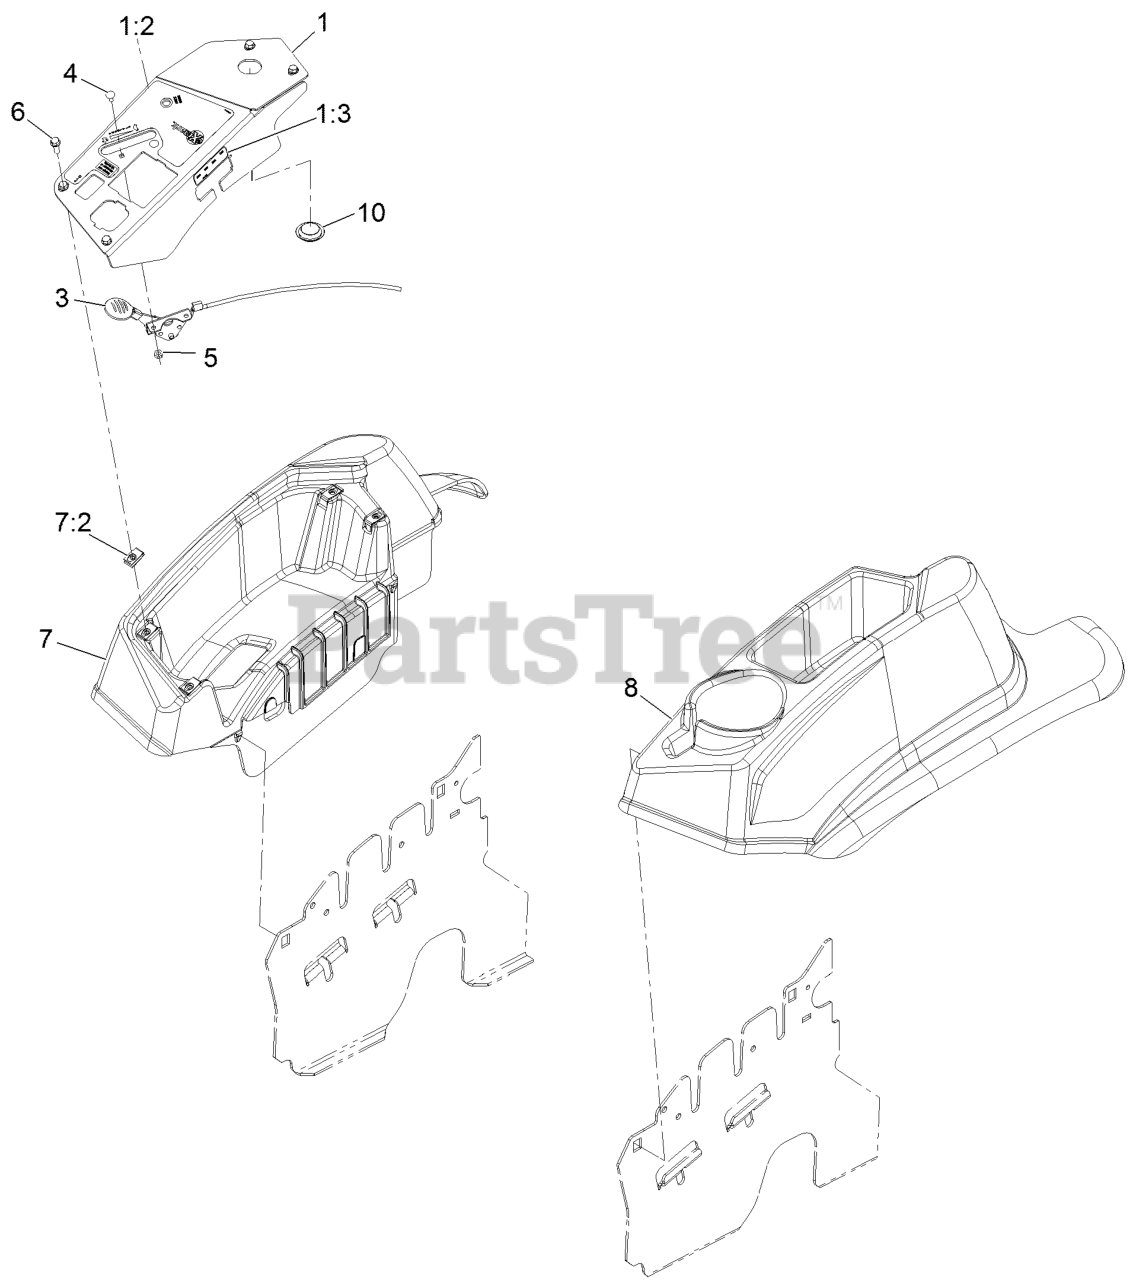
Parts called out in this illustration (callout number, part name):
1	ASM,CONTROL PANEL W/DECAL
1:2	DECAL,CONTROL PANEL EFI
1:3	DECAL-FUSE
3	ASM,THROTTLE CABLE
4	BOLT-CARR
5	NUT-LOCK, NI
6	SCREW-HWH
7	CONSOLE,RH AS ASM
7:2	Nut-Retainer-Panel 1/4-20
8	CONSOLE, LH AS
10	PLUG-PLASTIC
